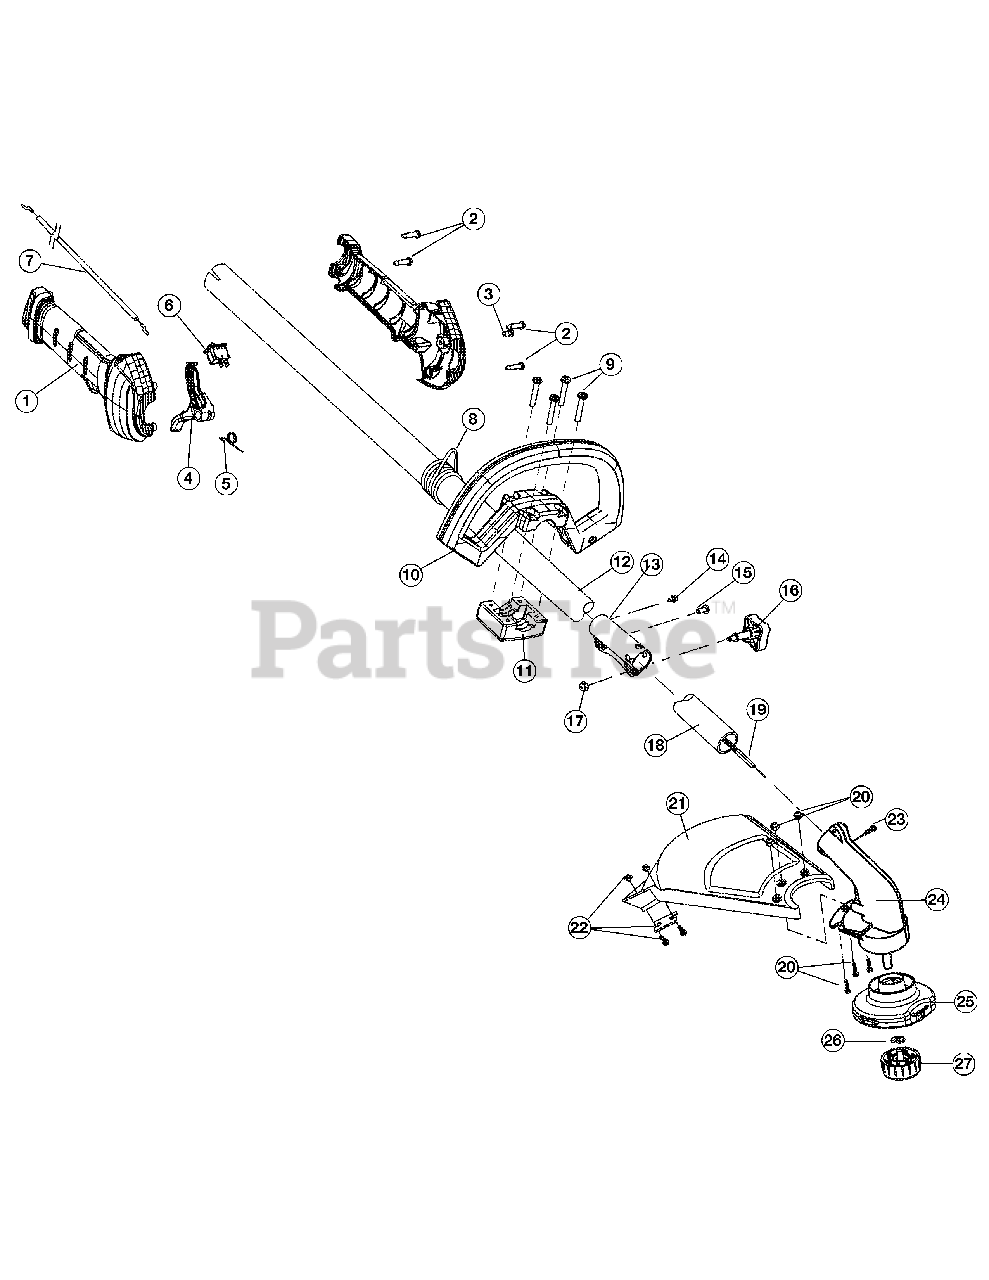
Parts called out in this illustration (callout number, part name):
1	Throttle Grip Assembly (includes 2-6)
2	Screw
3	Anti-Rotation Screw
4	Throttle Trigger
5	Throttle Trigger Spring
7	Throttle Cable
8	Harness Clip
11	D-Handle Base
12	Upper Drive Shaft Assembly
13	Split Boom Coupler Assembly (includes 14-17)
16	Knob (includes 17)
17	Nut
18	Lower Drive Shaft Housing Assembly
19	Lower Flex Shaft
20	Guard Mounting Screw Assembly
21	Gaurd Assembly (includes 22)
22	Blade Assembly
23	Anti-Rotation Screw
24	Gearbox Assembly
25	Fixed Head Line Assembly
26	Lock Washer
27	Bump Knob Assembly
